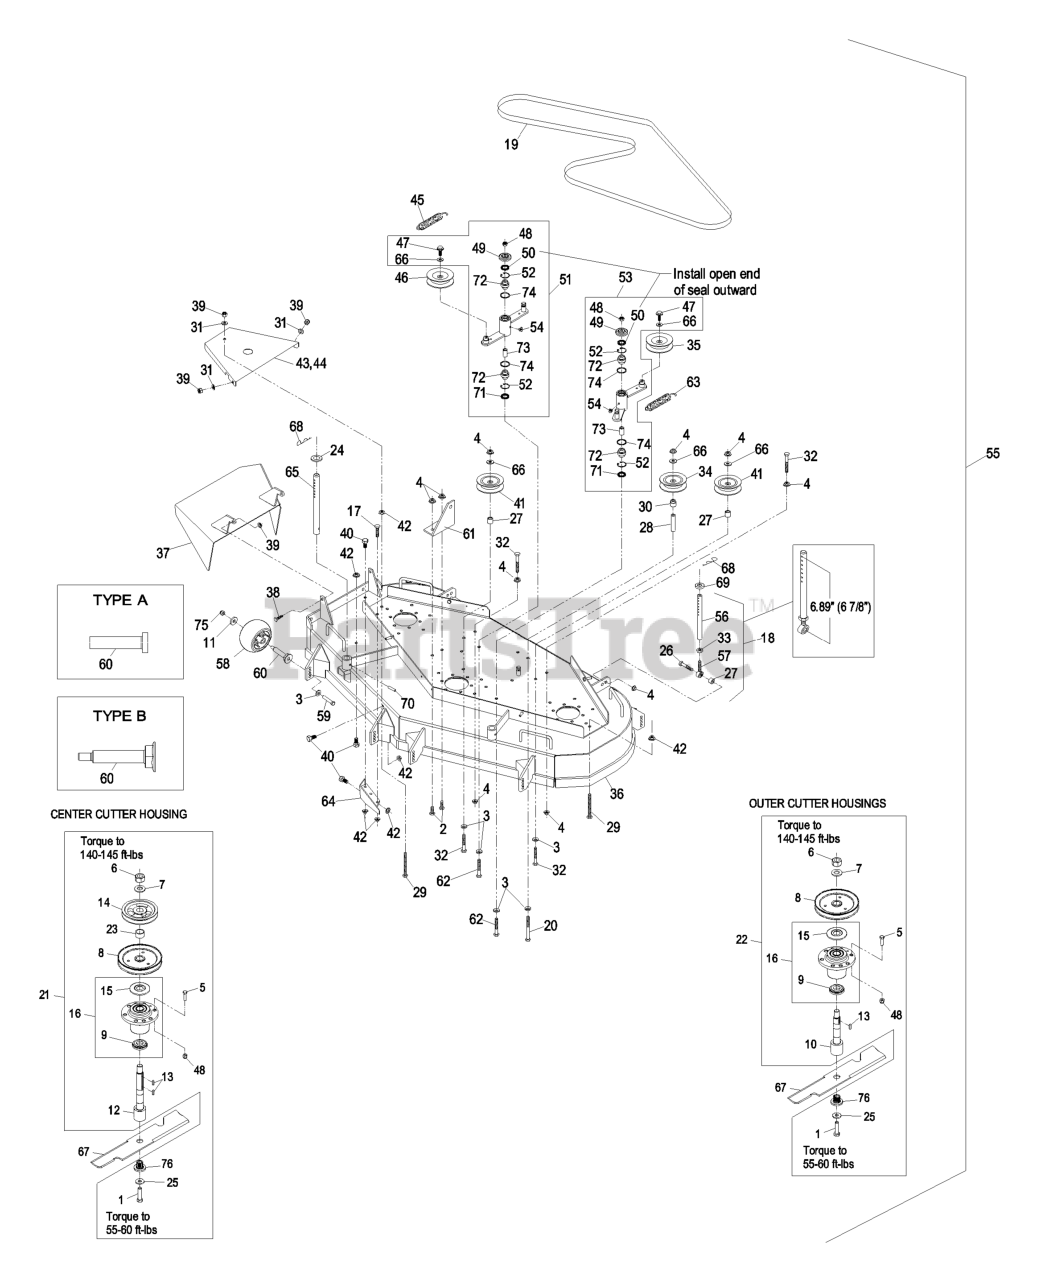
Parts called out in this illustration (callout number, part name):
1	SCREW-HH
2	SCREW-HH
3	WASHER-BELLEVILLE
4	NUT-HHF, WHIZ
5	SCREW-HH
6	NUT-HH
8	SHEAVE,BLADE DRIVE 6.30
9	SPACER-GUARD, BOTTOM
10	KIT, SPLINED SPINDLE 103-
12	KIT, SPLINED SPINDLE 103-
14	SHEAVE,BLADE DRIVE
15	GUARD-BEARING, TOP
16	KIT, CUTTER HOUSING
17	SCREW-HH
19	BELT,MULE DRIVE
20	SCREW-HH
21	ASM, CUTTER HSG FMD604CTR
22	ASM, CUTTER HSG COMPLETE
23	SPACER,TUBE
24	SPACER-DECK SUPPORT
25	WASHER-SPRING
26	SCREW-HH
28	SPACER-ANCHOR, CLUTCH
29	BOLT,TAP HH
30	BUSHING,IDLER
31	WASHER-FLAT
32	BOLT-CARR
33	NUT-HEX
34	PULLEY-IDLER
35	PULLEY-IDLER
36	ASM, DECK W/DECALS FMD604
37	WLD,CHUTE FMD604
38	SCREW-HH
39	NUT-LOCK, NI
40	SCREW-HH
41	IDLER,PULLEY
43	SHIELD,BELT RH
44	SHIELD,BELT LH
45	SPRING-EXTENSION
46	IDLER,PULLEY
47	SCREW-HHF
48	NUT-LOCK, NI
49	GUARD-TOP
50	SEAL-LIP, SINGLE
51	KIT, IDLER ARM W/BEARINGS
52	RING-SNAP
53	KIT, IDLER ARM W/BEARINGS
54	FITTING-GREASE, 90 DEG
55	Complete Deck Assy
56	LINK,SUPPORT
57	BALLJOINT
58	ROLLER-SCALP, ANTI
59	SCREW-HH
60	BUSHING-ROLLER
61	BRACKET,SPRING ANCHOR
62	SCREW-HH
63	SPRING-EXTENSION
64	WLD,BAFFLE DISCHARGE
65	ROD,DECK SUPPORT
66	WASHER-FLAT
68	PIN,HAIR COTTER
71	SEAL-LIP, DOUBLE
72	BEARING-SPHERICAL
73	BUSHING-LEVER, LIFT
75	NUT-HHF, WHIZ
76	BUSHING,SPLINED
